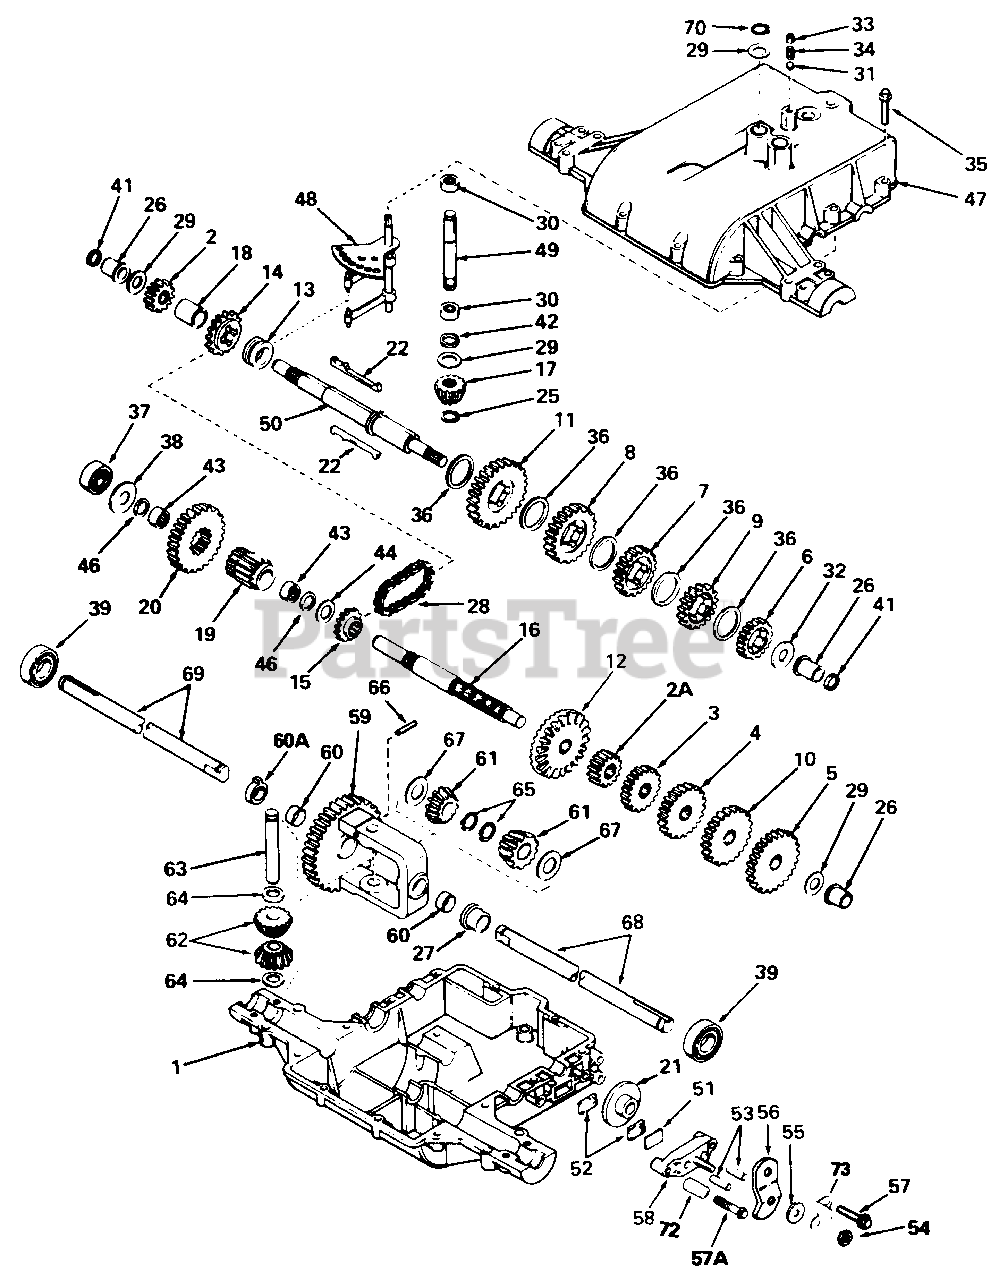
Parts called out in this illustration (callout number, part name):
1	CASE, Transaxle
2	GEAR, Spur (15 teeth)
2A	GEAR, Spur (12 teeth)
3	GEAR, Spur (20 teeth)
4	GEAR, Spur (25 teeth)
5	GEAR, Spur (30 teeth)
6	GEAR, Spur (20 teeth)
7	GEAR, Spur (25 teeth)
8	GEAR, Spur (30 teeth)
9	GEAR, Spur (22 teeth)
10	GEAR, Spur (28 teeth)
11	GEAR, Spur (37 teeth)
12	GEAR, Bevel (42 teeth)
13	COLLAR, Shift
14	SPROCKET (14 teeth)
15	SPROCKET (10 teeth)
16	SHAFT, Counter
17	BEVEL PINION, Input
19	PINION, Output
20	GEAR, Output
21	DISK, Brake
25	RING, Retaining
26	BUSHING, Flanged
27	BUSHING, Flanged
28	CHAIN, Roller (No. 41 chain, 22 links)
29	WASHER, Thrust
30	BEARING, Needle
31	BALL, Steel
32	WASHER, Thrust
33	SCREW, Set, 3/8-16 x 3/8
35	SCREW, Hex Hd. thread forming, 1/4-20 x 1-1/4
36	WASHER, Thrust
37	BEARING, Ball
38	WASHER, Flat
39	BEARING, Ball
41	SEAL, Square Cut
42	SEAL, Square Cut
43	BEARING, Needle
44	WASHER, Flat
46	SEAL, Square Cut
47	COVER, Transaxle
48	ROD & FORK ASSY., Shift
49	SHAFT, Input
50	SHAFT, Brake
51	PLATE, Brake Pad
52	PAD, Brake
53	PIN, Dowel
54	LOCKNUT, 5/16-24
55	WASHER, Flat
56	LEVER, Brake
57	SCREW, Hex Hd., thread forming, 1/4-20 x 1-1/4
57A	SCREW, Hex Hd., thread forming, 1/4-20 x 2-1/4
58	HOLDER, Brake Pad
59	GEAR ASSY., Differential (Incl. 2 of No. 60)
61	GEAR, Bevel
62	PINION, Bevel
63	PIN, Drive
64	WASHER, Thrust
65	RING, Retaining
66	PIN, Roll
67	WASHER, Thrust
68	AXLE (15-1/2" long)
69	AXLE (12-1/2" long)
70	RING, Retaining
